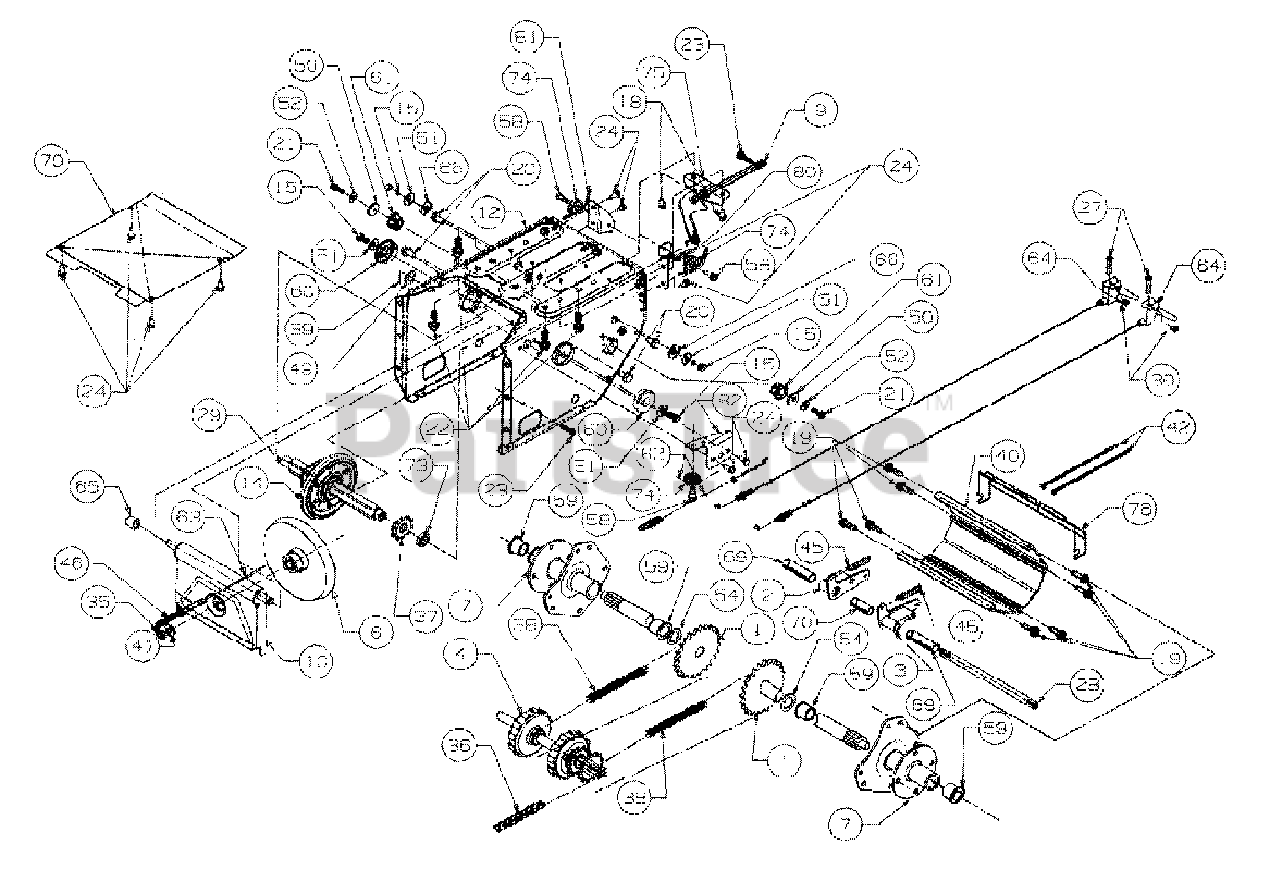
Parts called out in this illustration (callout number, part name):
1	Axle Assembly
2	Dog Assembly-R.H.
3	Dog Assembly -L.H.
4	Shaft Assembly
6	Disc Assembly
7	Hub Assembly
9	Rod Shift Assembly
10	Bracket Assembly
12	Frame Assembly
14	Wheel Assembly Friction
14	Rubber Only
15	Screw
18	Screw
19	Screw
21	Screw
23	Screw
24	Screw
27	Screw
28	Shaft
29	Shaft
30	Nut Flange
35	Nut Jam
36	Chain
37	Sprocket
38	Chain
39	Pin Cotter
40	Housing Track
42	Cable Tie
45	Spring
46	Spring
47	Washer-Bell
49	Washer-Flat
50	Washer-Flat
51	Washer-Bell
52	Washer-Bell
54	Washer-Flat
58	Screw-Shoulder
59	Bearing-Flange
60	Bearing-Ball
61	Bearing-Hex Flange
62	Cable-Auger Clutch
63	Cable-Drive Clutch
64	Cable with Trigger Lever
65	Spacer
66	Spacer-Shoulder
69	Spacer-Split
70	Spacer-Split
73	Spacer
74	Roller-Cable
79	Cover-Frame
80	Bracket-Guide
81	Bracket-Guide
82	Bracket-Guide
